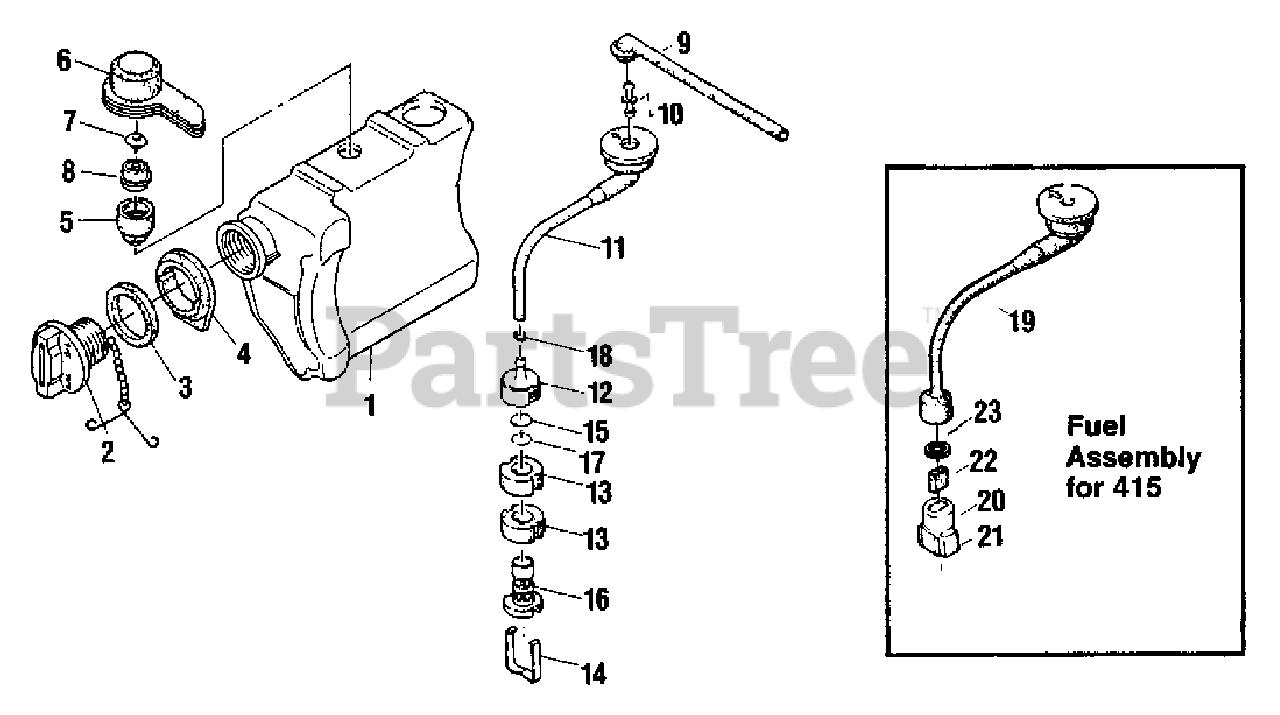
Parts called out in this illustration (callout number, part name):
1	TANK, FUEL
2	CAP, FUEL
3	GASKET, CAP
4	GASKET, FUEL CAP
5	HOLDER, VALVE
6	CAP, VENT
7	VENT ASSY
8	RETAINER
9	PIPE, FUEL
10	CONNECTOR, PIPE
11	PIPE, FUEL W/GROMMET
12	WEIGHT, FUEL LINE
13	ELEMENT, FUEL FILTER
14	CLIP, FILTER
16	BODY, FUEL FILTER
17	RING, RETAINING
18	CLIP Ø6
19	PIPE, FUEL
20	WEIGHT
21	FILTER, FUEL - A
22	FILTER, FUEL - B
23	CLIP
